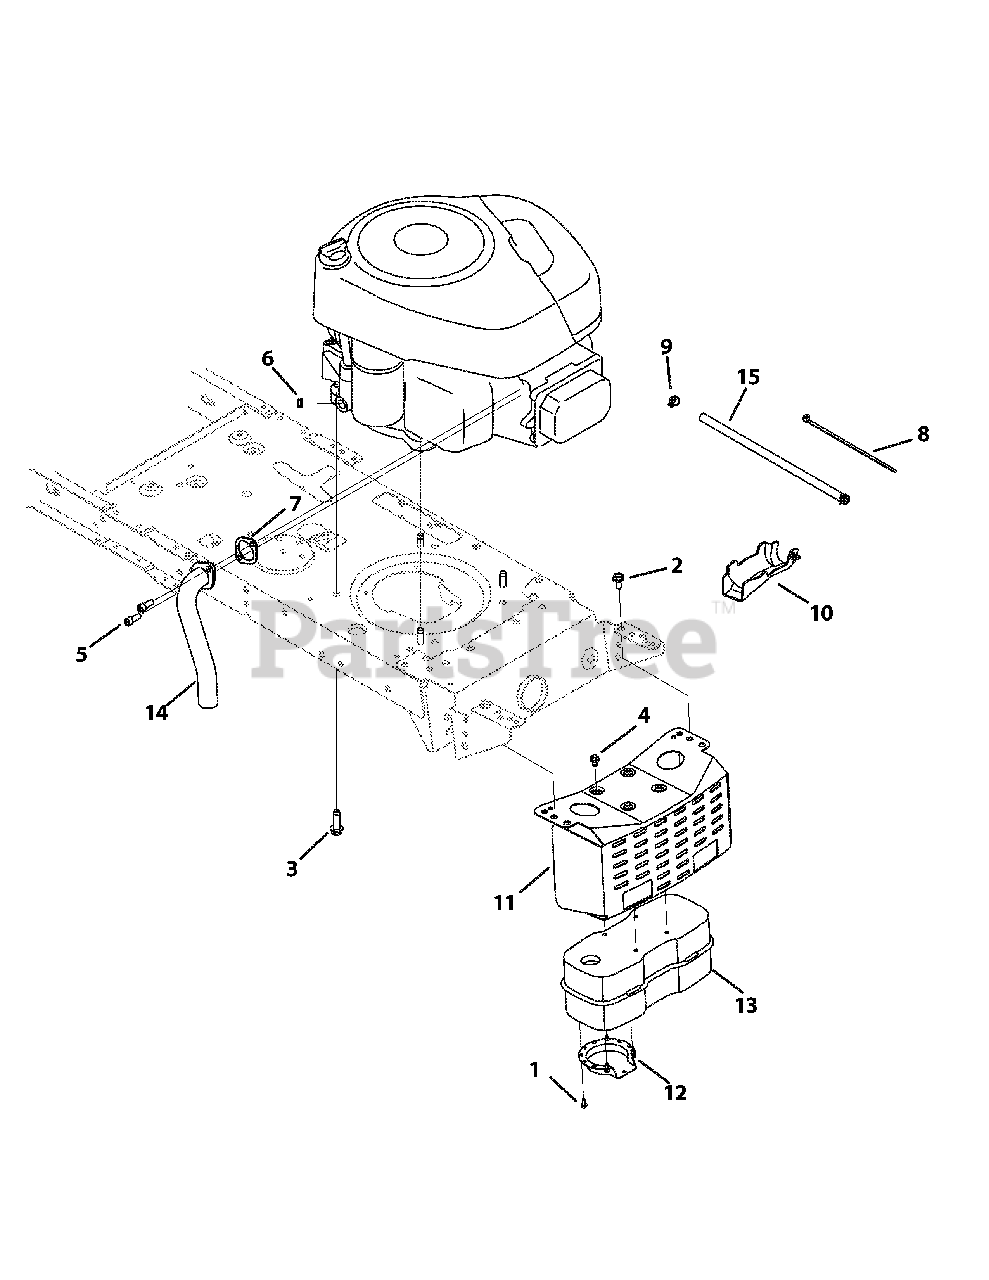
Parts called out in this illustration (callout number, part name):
1	Screw, 8-18 x .500
2	Screw, 5/16-18 x .750
3	Screw, 3/8-16 x 1.000
4	Screw, 1/4-20 x .500
5	Socket Screw, 5/16-18 x .750
6	Sems Nut, 1/4-20
7	Exhaust Gasket, 10 HP Briggs
8	Cable Tie
9	Hose Clamp, .490 Diameter
10	Oil Drain Sleeve
11	Muffler Bracket
12	Muffler Deflector
13	Single Inlet Muffler
14	Exhaust Pipe, Single Briggs
15	Fuel Hose, Low Permeation
